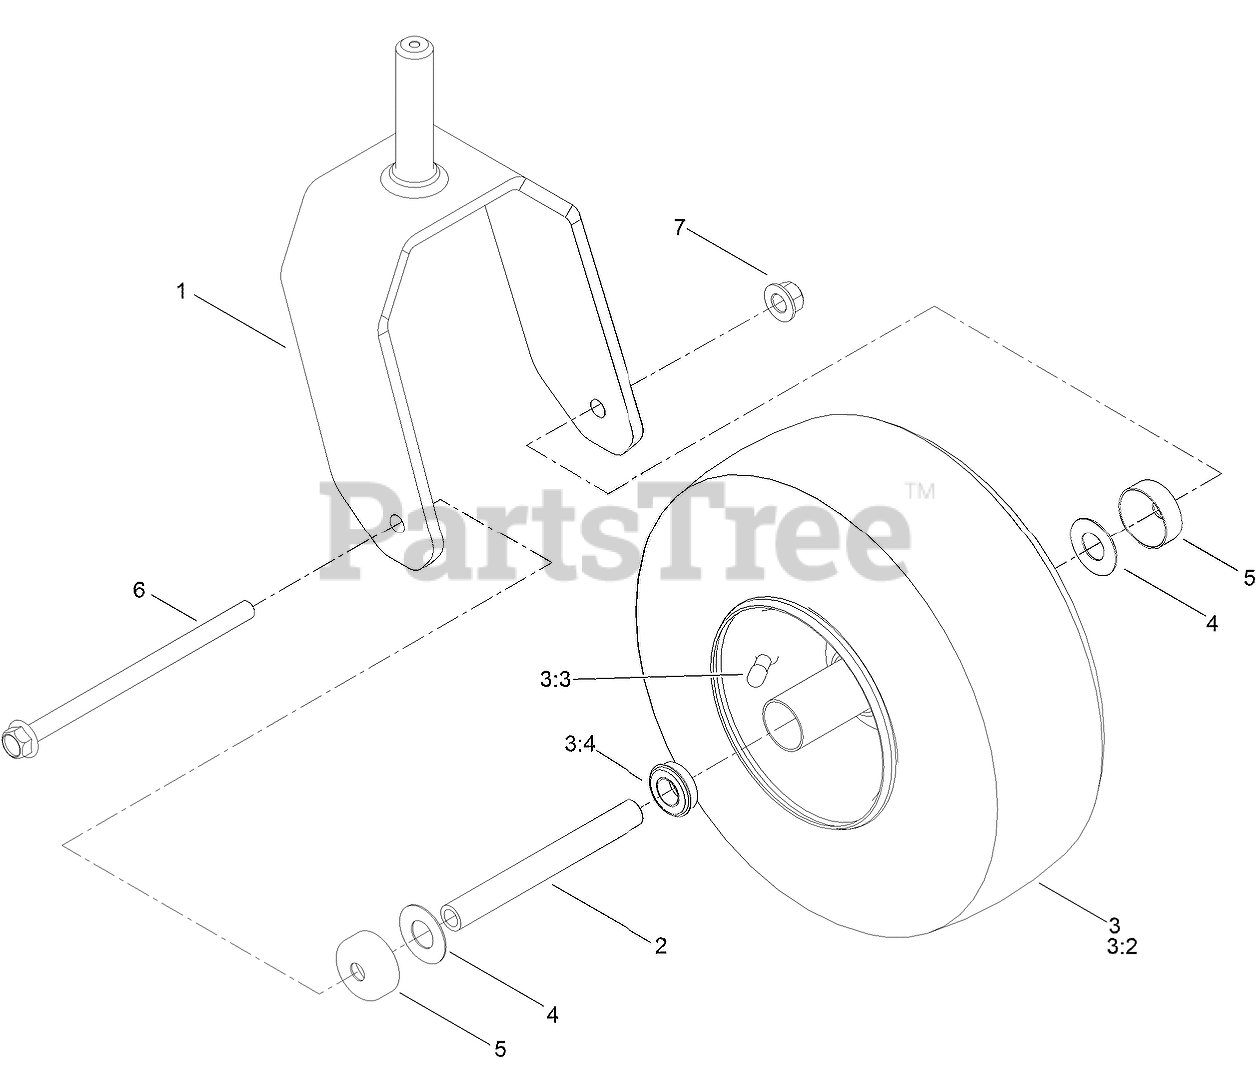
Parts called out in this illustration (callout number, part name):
1	CASTER FORK [BLACK]
2	SPANNER-WHEEL
3	TIRE AND WHEEL ASM
3:4	BEARING
4	WASHER
5	GUARD-SEAL
6	SCREW-HHF
7	NUT-LOCK
